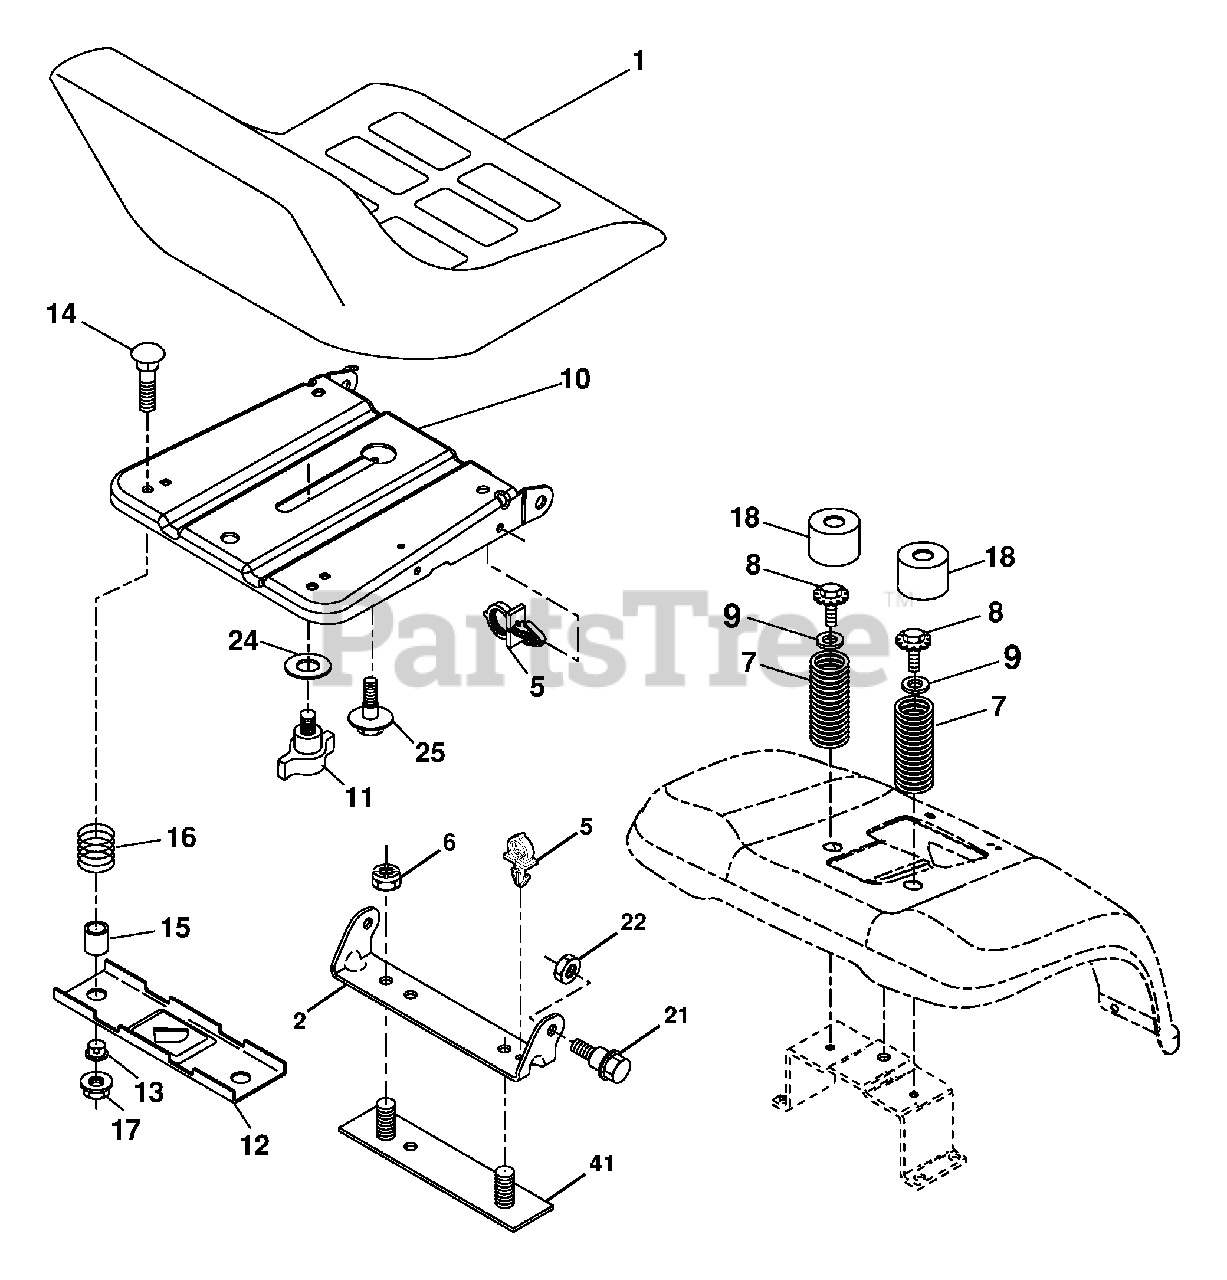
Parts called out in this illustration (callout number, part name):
1	Seat
2	Bracket Pivot Seat 8 720
5	Clip Push-In
6	Nut Hex w/Ins. 3/8-16 unc
7	Spring Seat Cprsn 2 250 Blk Zi
8	Screw 3/8-16 x 1.5 Smgml
9	Washer 13/32 x 1 x 14 Ga.
10	Pan Seat
11	Knob Seat
12	Bracket Mounting Switch
13	Bushing Snap Blk Nyl 50 Id
14	Bolt Rdhd Sqnk 1/4-20 x 1-1/2
15	Spacer Split 28 x 96
16	Spring Cprsn
17	Nut Lock 1/4 Lge Flg Gr. 5 Zinc
18	Cap Spring Seat
21	Bolt Shoulder 5/16-18 unc
22	Nut Hex Lock W/Ins 5/16-18
24	Washer 17/32 x 1-3/16 x 12 Ga.
25	Bolt Shoulder 5/16-18 x 62
41	Strap Asm. Fender
